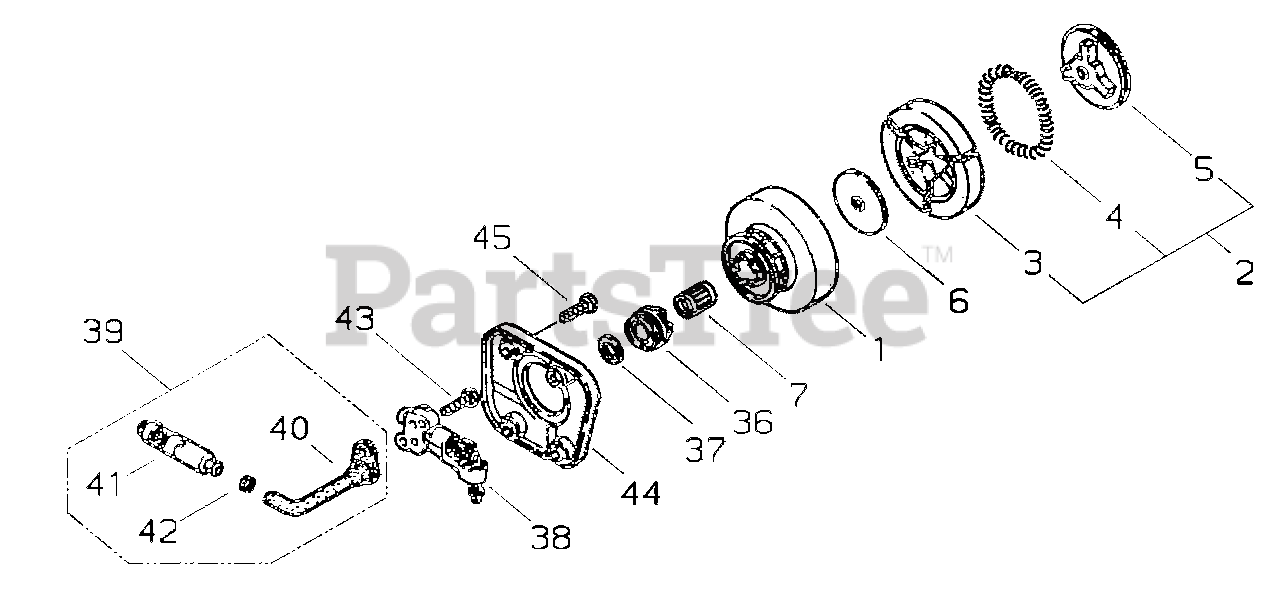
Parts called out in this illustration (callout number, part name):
1	DRUM, CLUTCH
2	CLUTCH ASSY
3	SHOE, CLUTCH
4	SPRING, CLUTCH
5	BOSS, CLUTCH
6	WASHER, CLUTCH
7	BEARING, NEEDLE
36	GEAR
37	PLATE, THRUST
38	AUTO-OILER ASSY
39	PIPE ASSY, OIL
40	PIPE, OIL
41	FILTER, OIL
42	CLIP
43	SCREW, ADHESIVE M4×12
44	COVER, PUMP
45	SCREW, ADHESIVE M4×12
